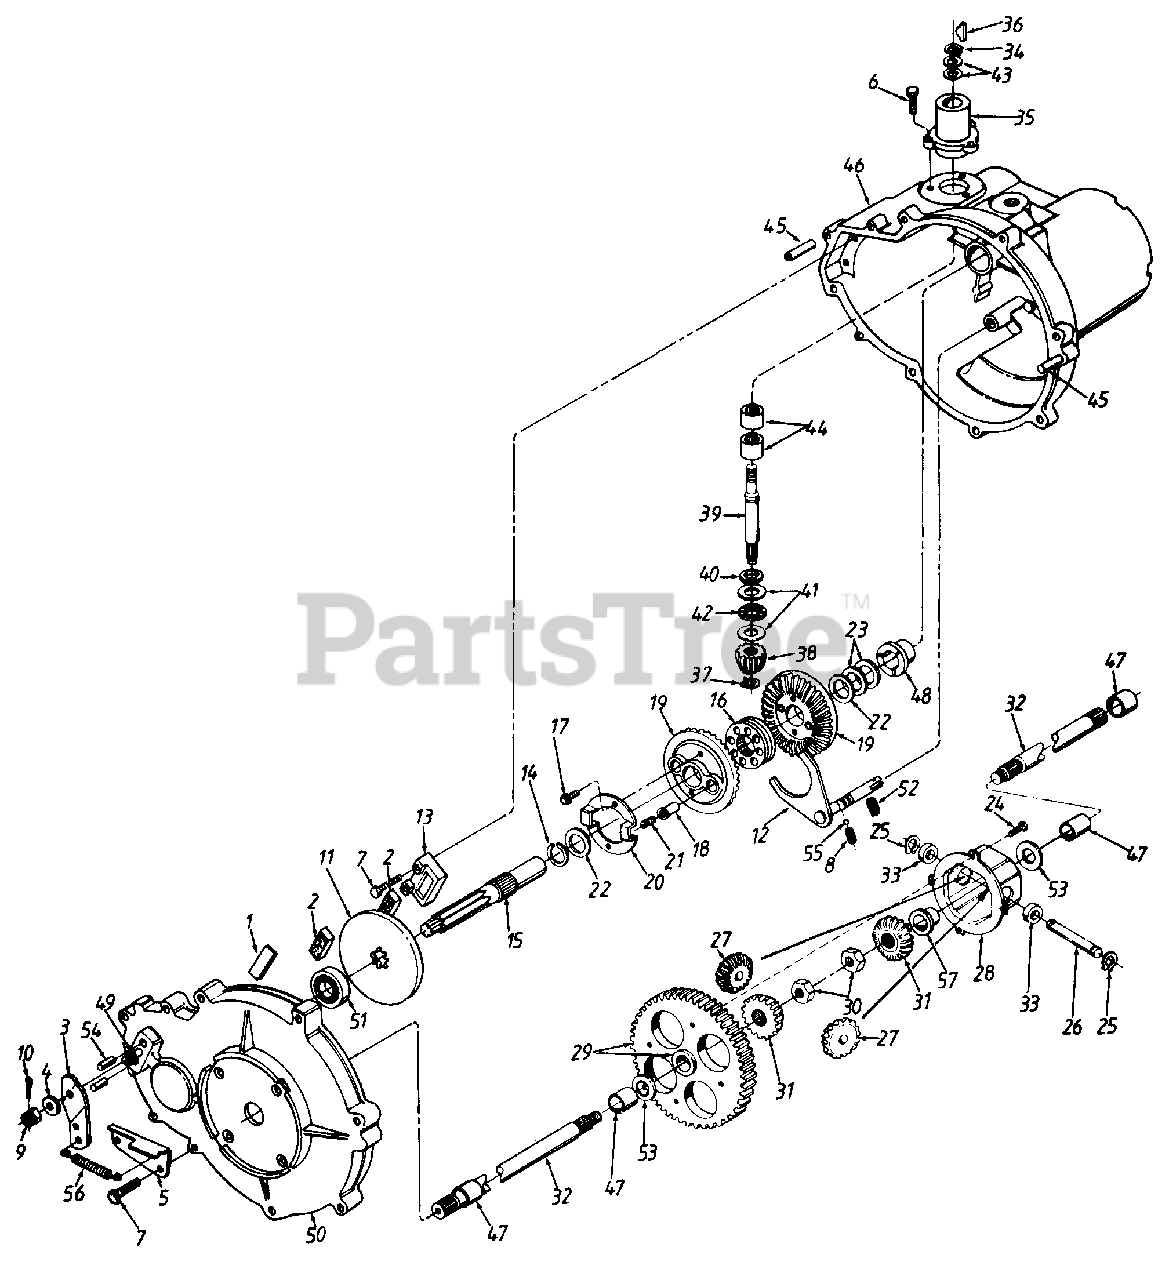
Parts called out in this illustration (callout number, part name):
1	Puck Plate
2	Brake Puck
3	Actuating Arm
4	Fl-Wash. 11/32" I.D. x 7/8" O.D.
5	Brake Stop Brkt.
6	Hex Bolt 1/4-20 x .62" Lg.
7	Hex Tap Scr. 1/4-20 x 1.25" Lg.
8	Spring Detent
9	Castle Nut 5/16-24 Thd.
10	Cotter Pin 3/32" Dia. x 1" Lg.
11	Brake Disc
12	Shifter Ass'y.
13	Brake Puck Holder
14	Retaining Ring
15	Shaft Drive
16	Shift Collar
17	Hex Wash. Hd. Tap Scr. 1/4-20 x.38" Lg.
18	Drive Pin
19	Bevel Gear Ass'y.
20	Spring Retaining Plate
21	Drive Spring
22	Fl-Wash. .915" I.D. x 1.5" O.D.
23	Fl-Wash. .915" I.D. x 1.37" O.D.
24	Pan Hd. Scr. 1/4-20 x .5" Lg.
25	Snap Ring
26	Cross Shaft
27	Miter Gear 15T
28	Differential Can Assembly
29	Differential Gear Ass'y. w/Bearing
30	Hex Ins. L-Nut 1/2-20 Thd.
31	Miter Gear
32	Axle
33	Differential Thrust Spacer
34	Snap Ring
35	Input Bearing Housing
36	#4 Hi-Pro Key 3/32" x 5/8" Dia.
37	Retaining Ring
38	Pinion Input 14T
39	Input Shaft
40	Seal 5/8" I.D.
41	Thrust Wash. .621" I.D. x 1.12"
42	Thrust Bearing
43	Fl-Wash. 5/8" I.D. x 1.0" O.D.
44	Needle Brg. 5/8" x 1/2" Lg.
45	Dowel Pin
46	R.H. Housing
47	Sleeve Bearing 3/4" I.D.
48	Flange Bearing .906" I.D.
49	Sq. Head Bolt 5/16-24 Thd.
50	L.H. Housing
51	Ball Bearing .669" I.D.
52	Set Screw 5/16-18 x 3/8" Lg.
53	Fl-Wash. .76" I.D. x 1.5" O.D.
54	Brake Actuating Pin
55	Ball Detent
56	Ext. Spring 1.14" Lg.
57	Differential Flange Brg.
